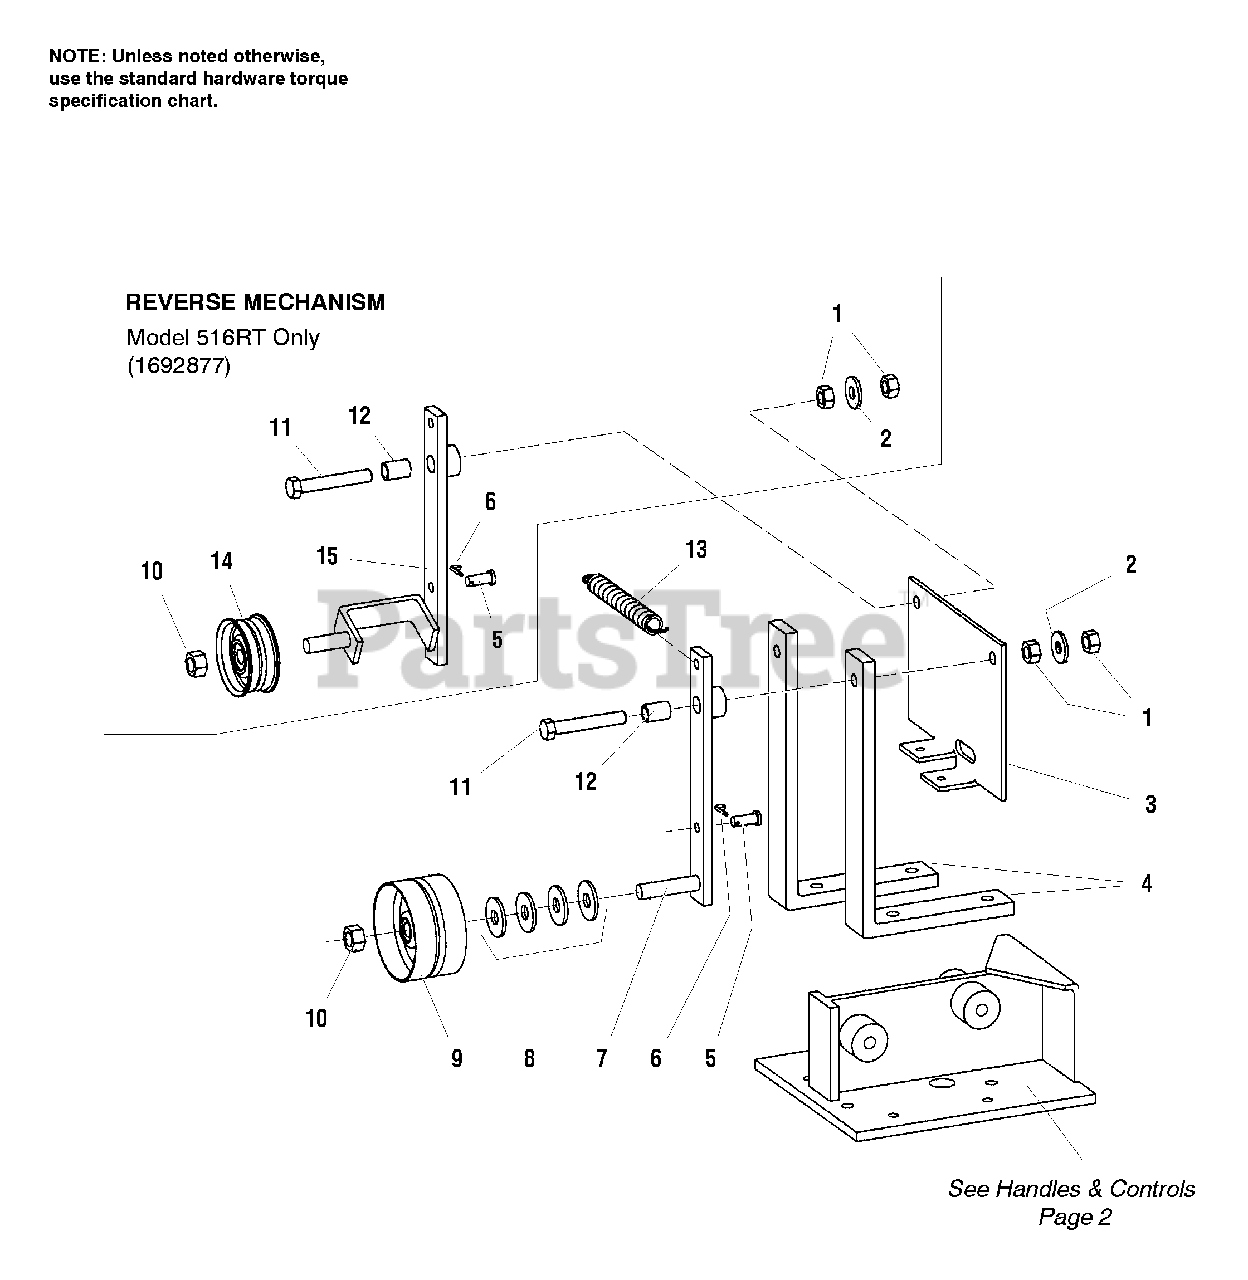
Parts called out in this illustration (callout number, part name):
1	NUT, 5/16"-18
2	WASHER, Flat, 5/16"
3	BRACKET, Cable Mount
4	MOUNTING BAR, Shifting Mechanism
5	LINK PIN
6	COTTER PIN
7	IDLER ARM, Forward
8	WASHER, Flat, 3/8"
9	PULLEY, Forward Idler
10	NUT, Hex, 3/8"-16
11	CAPSCREW, Hex Head 5/16-18 x 2 G5
12	BUSHING, Pivot, 5/16"
13	SPRING, Idler Arm
14	PULLEY, Reverse Idler
15	IDLER ARM, Reverse
